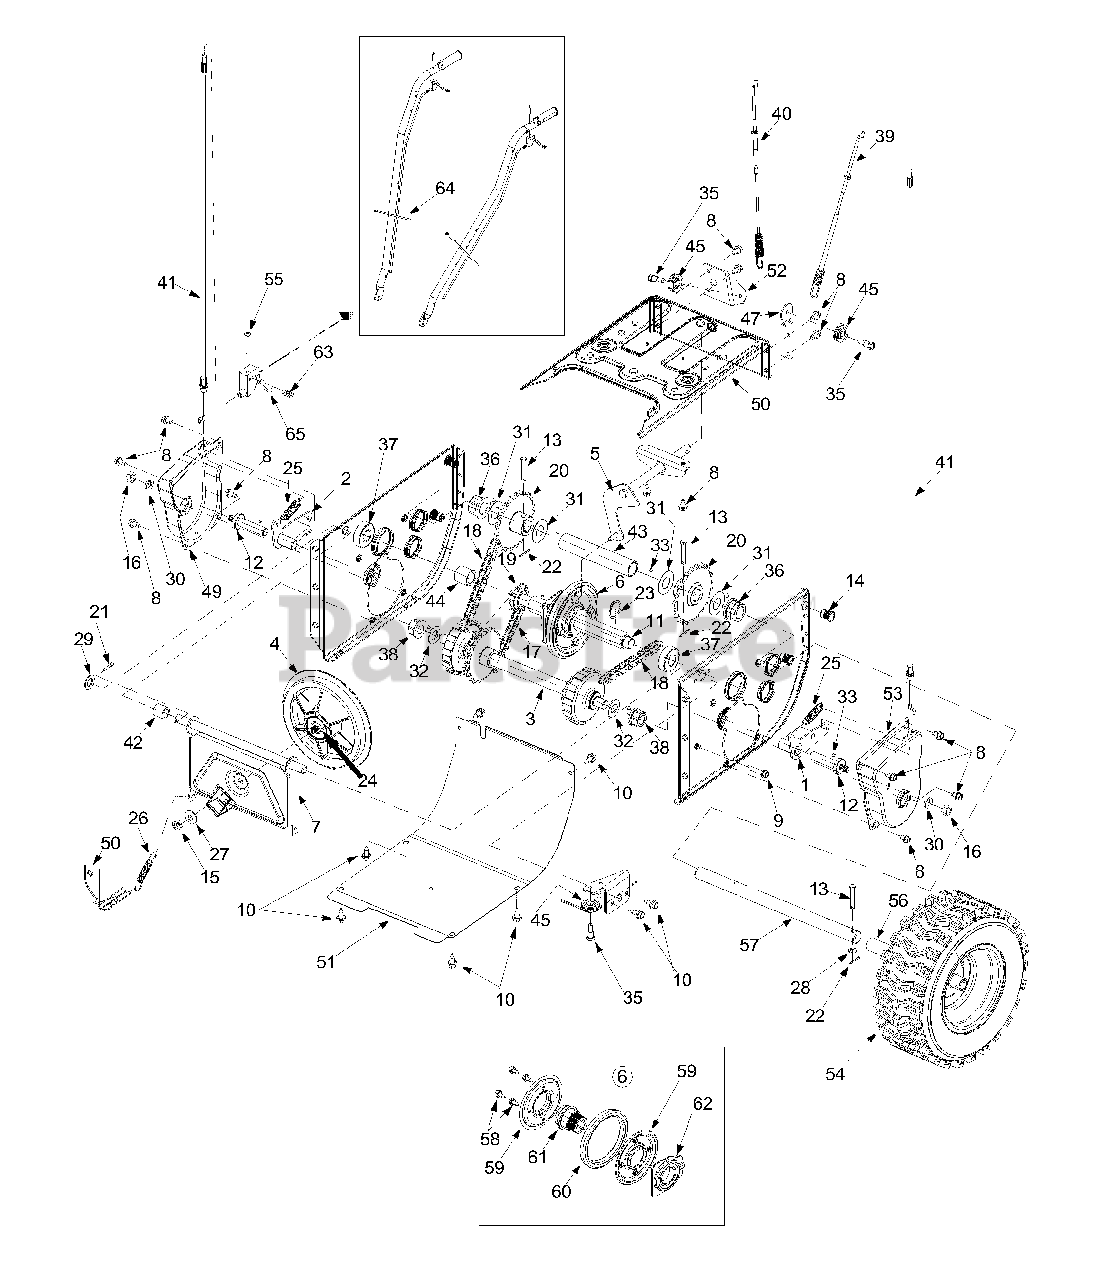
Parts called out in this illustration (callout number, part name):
1	Dogg Assembly RH
2	Dogg Assembly LH
3	Drive Shaft
4	Friction Wheel Disc Assembly
6	Friction Wheel Assembly
7	Support Bracket
8	TT screw 1/4-20 x 0.5"
9	TT Screw 1/4-20 x 1.25"
10	TT Screw 1/4-20 x .625"
11	Drive Shaft
12	Actuator Shaft
13	Clevis Pin
14	Nut Insert
20	Sprocket
21	Hairpin Clip
22	Hairpin Clip
23	Snap Ring
24	Loctite (TM)
25	Extension Spring
26	Extension Spring
27	Bell Washer
28	Flat Washer
29	Flat Washer
30	Lock Washer
31	Flat Washer
32	Flat Washer
33	Loctite (TM)
35	C Screw 1/4-28 x .375"
36	Hex Flange Bearing
37	Ball Bearing
38	Hex Flange Bearing
39	Auger Clutch Cable
40	Drive Clutch Cable
41	Steering Cable
43	Support Tube: Axle
45	Cable Roller
55	Oval C-Sunk Machine Screw
56	Spacer
57	Axle: Wheel
58	TT Screw 1/4-20 x .625"
59	Friction Plate
60	Friction Wheel Rubber
61	Friction Wheel Hub
62	Friction Wheel Bearing
64	Cable Tie
65	Turn Trigger
